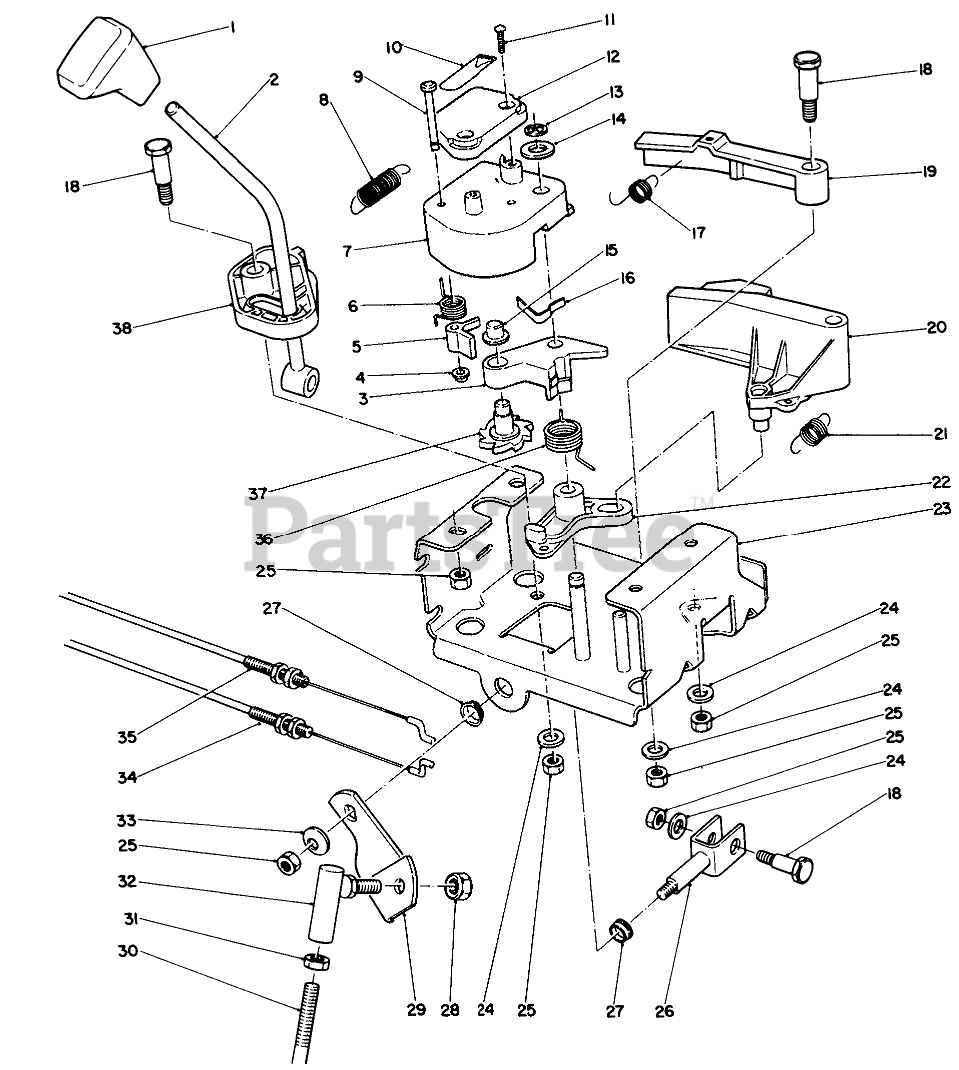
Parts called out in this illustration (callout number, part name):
1	KNOB-SHIFT
2	SHIFT ROD WA
3	LEVER-WHEEL, INDEX
4	NUT-PUSH
5	TANG-INDEX
6	SPRING-TORSION
7	LATCH-LEVER
8	SPRING-EXTENSION
9	PIN-TANG
10	DECAL
11	SCREW-PPH
12	COVER-LATCH
13	RING-RETAINING
14	WASHER-THRUST
15	RETAINER-PUSH ON
16	SPRING-FLAT
17	SPRING-EXTENSION
18	SCREW-SHOULDER
19	LEVER-LOCKOUT
20	LEVER-REVERSE
21	SPRING-EXTENSION
22	LEVER-REVERSE, SWITCH
23	Frame-Control
24	WASHER-PLAIN
25	NUT-LOCK, NI
26	CLEVIS WA
27	BUSHING
28	NUT-LOCK
29	BRACKET-SHIFT
30	ROD-BENT SHIFT, LOWER
31	NUT-HJ
32	JOINT-BALL
33	WASHER-BELLEVILLE
34	CABLE-GEARBOX
35	CABLE-ARM, LATCH
36	SPRING-TORSION
37	WHEEL-INDEX
38	BASE-LOCKOUT
